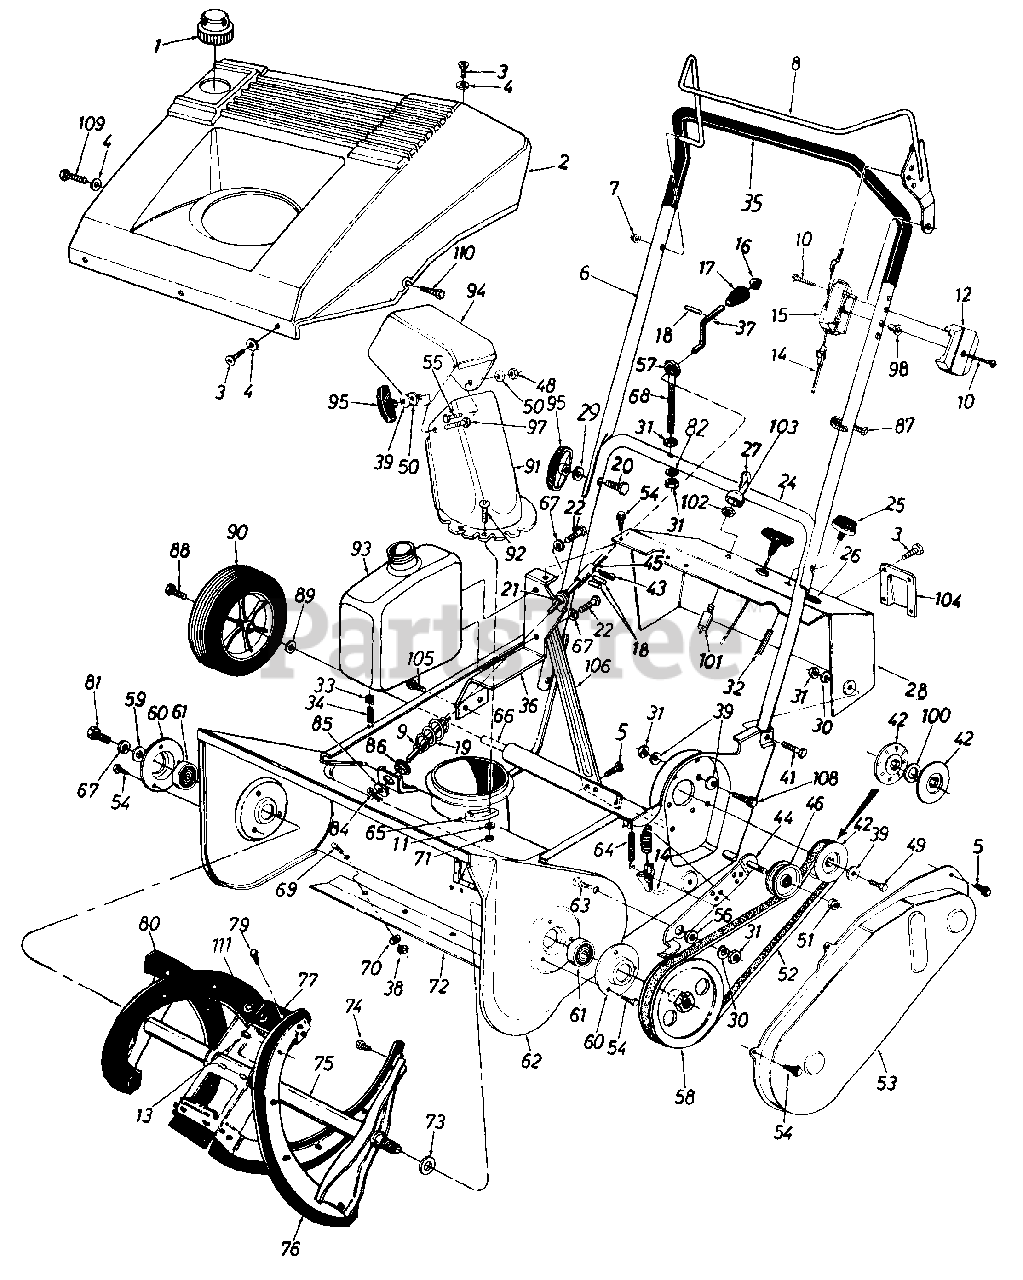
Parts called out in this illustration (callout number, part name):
1	Gas Tank Cap
2	Shroud
3	Hex B-Tap Scr. #10 x .5" Lg.
4	Fl-Wash. .203" I.D. x .41"
5	Hex L-Wash. Hd. AB-Tap 1/4 x .62" Lg.
8	Control Handle Ass'y. - L.H.
9	Fl-Wash. .385" I.D. x .62"
10	Truss Mach. Hi-B Tap Scr. #12 x 1.5" Lg.
11	Fl-Wash. .281" I.D. x .5" O.D.
12	Control Panel Half
13	Pop Rivet .187" Dia.
14	Clutch Cable 35" Lg.
15	Control Panel Half
16	Push Cap 3/8" Rod
17	Knob - 3/8" Dia. Hole
18	Roll Pin 1/8" Dia. x .63" Lg.
19	Lower Chute Crank Ass'y.
20	Curved Carriage Bolt 5/16-18 x 1.75" Lg.
21	Chute Crank Grommet
22	Hex Bolt 1/4-20 x .5" Lg.
24	Lower Handle
26	Plastic Plug
30	L-Wash. 5/16" I.D.
31	Hex Nut 5/16-18 Thd.
32	Primer Hose - 9" Lg.
33	Hose Clamp - 1/2" O.D.
34	Gas Line - 26" Lg.
35	Foam Grip 22" Lg.
36	Gas Tank Support Brkt.
37	Upper Chute Crank
38	Hex Jam Nut 1/4-20 Thd.
39	Bell-Wash. .345" I.D. x .88"
41	Hex Bolt 5/16-18 x 1.5" Lg.
42	3/8" "V"-Pulley Half .625" I.D. x 6.0" O.D.
43	Cotter Pin 3/32" Dia.
44	Idler Brake Brkt. Ass'y.
45	Spacer .38" I.D. x 1.12" Lg.
46	Fl-Idler w/Flanges 2.12" O.D.
48	Hex L-Nut 5/16-18 Thd.
49	Hex Bolt 5/16-24 x .75" Lg.
50	Fl-Wash. .344" I.D. x 1.25"
51	Hex Patch L-Nut 3/8-24 Thd.
52	V-Belt
54	Hex B-Tap Scr. 1/4" x .38" Lg.
55	Carriage Bolt 5/16-18 x .75"
56	Shld. Spacer .50" Dia. x .27"
57	Plastic Bushing .38" I.D.
58	1/2" "V"-Pulley 1/2-20 L.H. x 6"
59	Fl-Wash. 1/4" I.D. x .93" O.D.
60	Bearing Cup
61	Ball Brg. .669" I.D. x 1.574"
64	Extension Spring 1.12" Lg.
65	Chute Flange Keeper
66	Wheel Axle 20.6" Lg.
67	L-Wash. 1/4" I.D.
68	Eyebolt
69	Carriage Bolt 1/4-20 x .50"
70	Fl-Wash. .281" I.D. x .73"
71	Hex L-Nut 1/4-20 Thd.
72	Shave Plate
73	Fl-Wash. .510" I.D. x 1.0" O.D.
74	Hex Wash. B-Tap Scr. 1/4 x .62" (Spec.)
75	Auger Ass'y.
76	Rubber Spiral - L.H.
77	Rubber Paddle
79	Hex Wash. B-Tap Scr. #10 x .62" Lg.
80	Rubber Spiral - R.H.
81	Hex Wash. TT-Tap Cl-Scr. 1/4-20 x .75" Lg.
82	Saddle Wash. .32" I.D.
84	Cotter Pin 3/32" Dia. x .75"
85	Fl-Wash. .406" I.D. x 1.25"
86	Hex Bushing .385" I.D.
87	Cable Tie
88	Hex Tap Scr. 3/8-24 x .88" Lg.
89	Fl-Wash. .510" I.D. x .75"
90	7" Wheel & Tire Ass'y.
91	Lower Chute
92	Truss Mach. Scr. 1/4-20 x .75"
93	Fuel Tank - Two Qt.
94	Upper Chute
95	Knob Handle Ass'y.
97	Carriage Bolt 5/16-18 x 1"
98	Control Disc Pin
100	Fl-Wash. .635" I.D. x .93" O.D. x .06"
101	Key Switch
102	Ignition Switch Nut 5/8-32 Thd.
103	Ignition Switch Cap
104	Choke Cover
105	Hex Wash. Hd. Tap Scr. 1/4-.5" Lg.
109	Pan Hd. Tap Scr. #10 x 1.25" Lg.
110	Hex Wash. Hd. Tap Scr. 1/4-20 x 1" Lg.
111	Torx AB-Tap Scr. 1/4 x .62" Lg.
